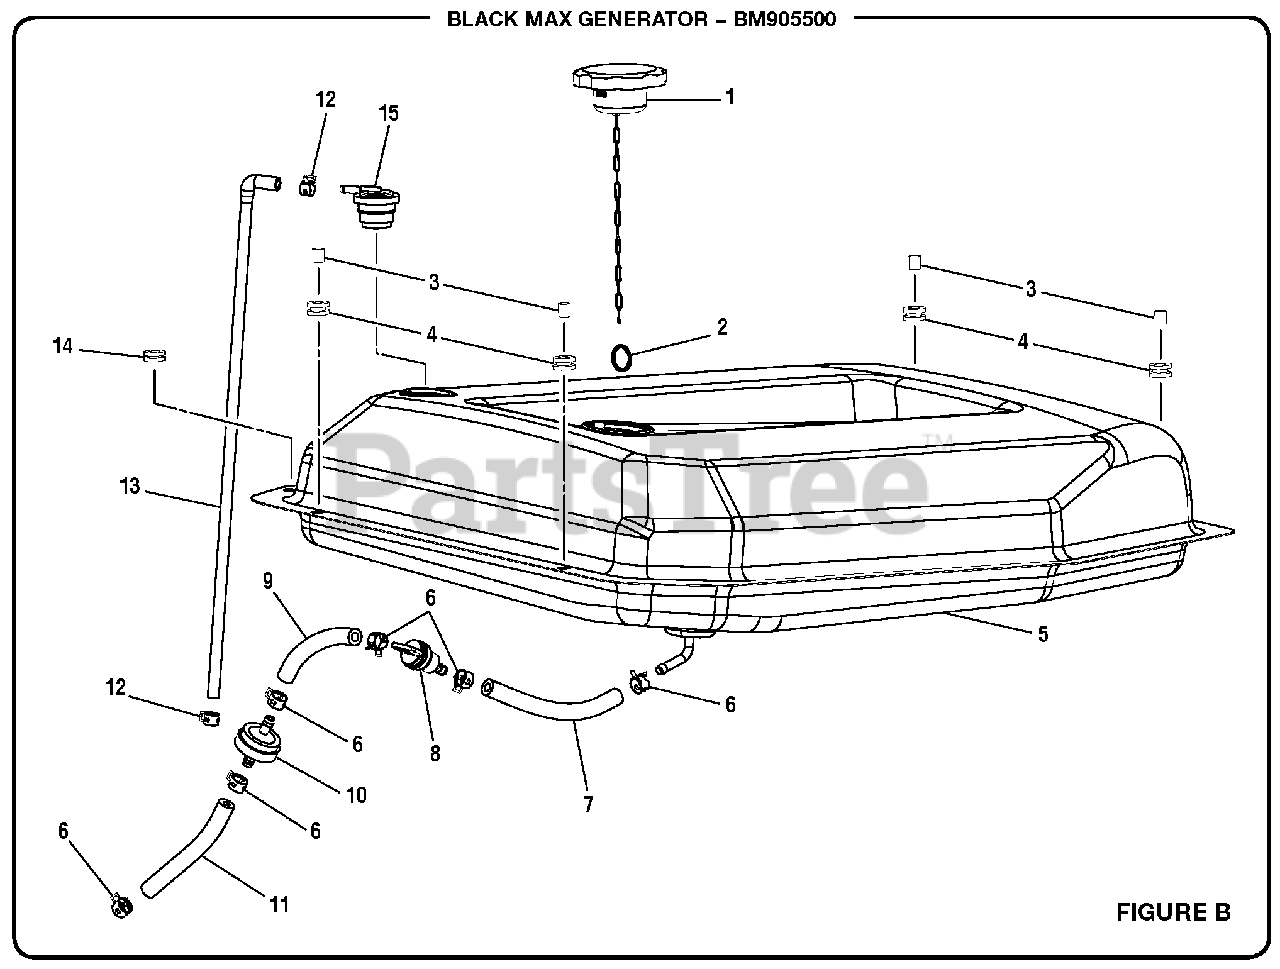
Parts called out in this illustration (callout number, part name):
2	Ring Clip
3	Spacer (Fuel Tank Isolator)
4	Bushing (Fuel Tank Isolator)
5	Fuel Tank
6	Fuel Line Clamp (1/2 in.)
7	Fuel Line (133 mm)
8	Fuel Shut Off Valve
9	Fuel Line (85 mm)
10	Fuel Filter
11	Fuel Line (233 mm)
12	Fuel Line Clamp (7/16 in.)
13	Vapor Hose (410 mm)
14	Fuel Hose Protector
15	Fuel Tank Vapor Vent
